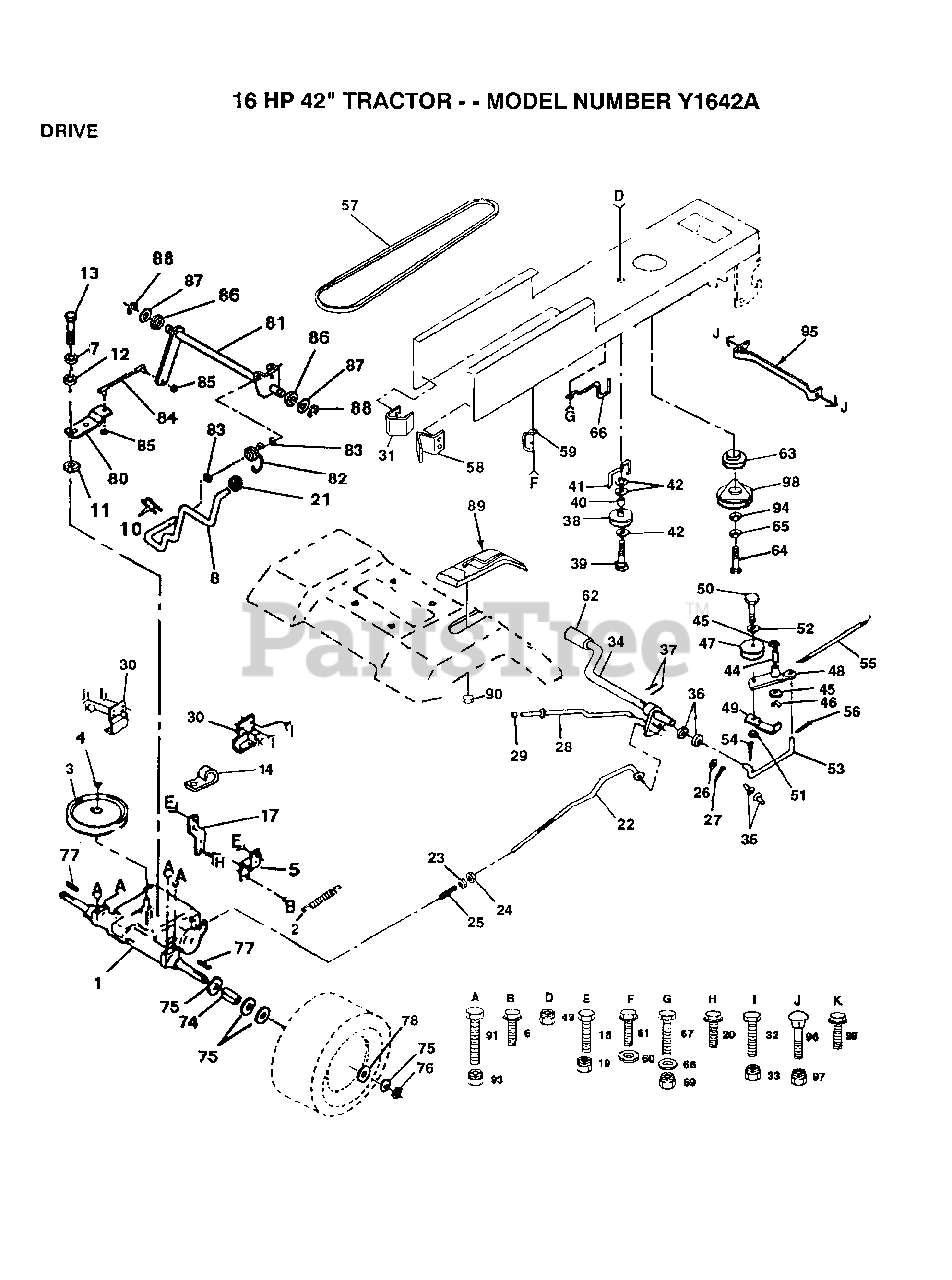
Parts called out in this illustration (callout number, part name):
3	PULLEY TRANS
5	STRAP TORQUE
6	SCREW
7	LOCKWASHER
10	PIN COTTER 1/8
11	WASH-SHFT PLT LT
12	WASHER
14	CLIP T
17	STRAP TORQUE
20	SCREW
21	KNOB.DUCKHEAD.1/2
22	BRAKE ROD
23	NUT
24	NUT
25	SPRING ROD LT
26	WASHER
27	COTTER PIN
28	BRAKE PARK ROD
29	PLUNGER CAP T
30	TRANSAXLE MTG BKT
32	BOLT
35	NYLON BEARING
36	WASHER LT
38	PULLEY.IDLER.FLAT
39	BOLT
40	SPACER T
41	BELT KEEPER LT
42	WASHER
44	"LY, BEARING"
45	WASHER LT
46	KLIP RING
48	ARM IDLER
49	RETAIN BELT
52	WASHER
53	"LINK, CLUTCH T"
54	COTTER PIN
55	"SPRING, RETURN LT"
56	COTTER PIN
58	"KEEPER,BELT RH T"
60	WASHER
61	SCREW
62	PEDAL COVER T
65	LOCKWASHER
66	KEEPER.BELT.ENG.L
67	BOLT
68	WASHER
74	SPACER LT
75	WASHER
76	E-RING LT
77	SQUARE KEY
78	WASHER
80	SHIFT LEVER
81	SHAFT ASM SHIFT
82	"SPRING,TORSION"
83	WASHER
84	TIE ROD
85	NUT 1/4-28
86	BUSHING
87	WASHER D
88	KLIP RING
90	NUT
91	BOLT
94	WASHER
96	BOLT
99	SCREW
